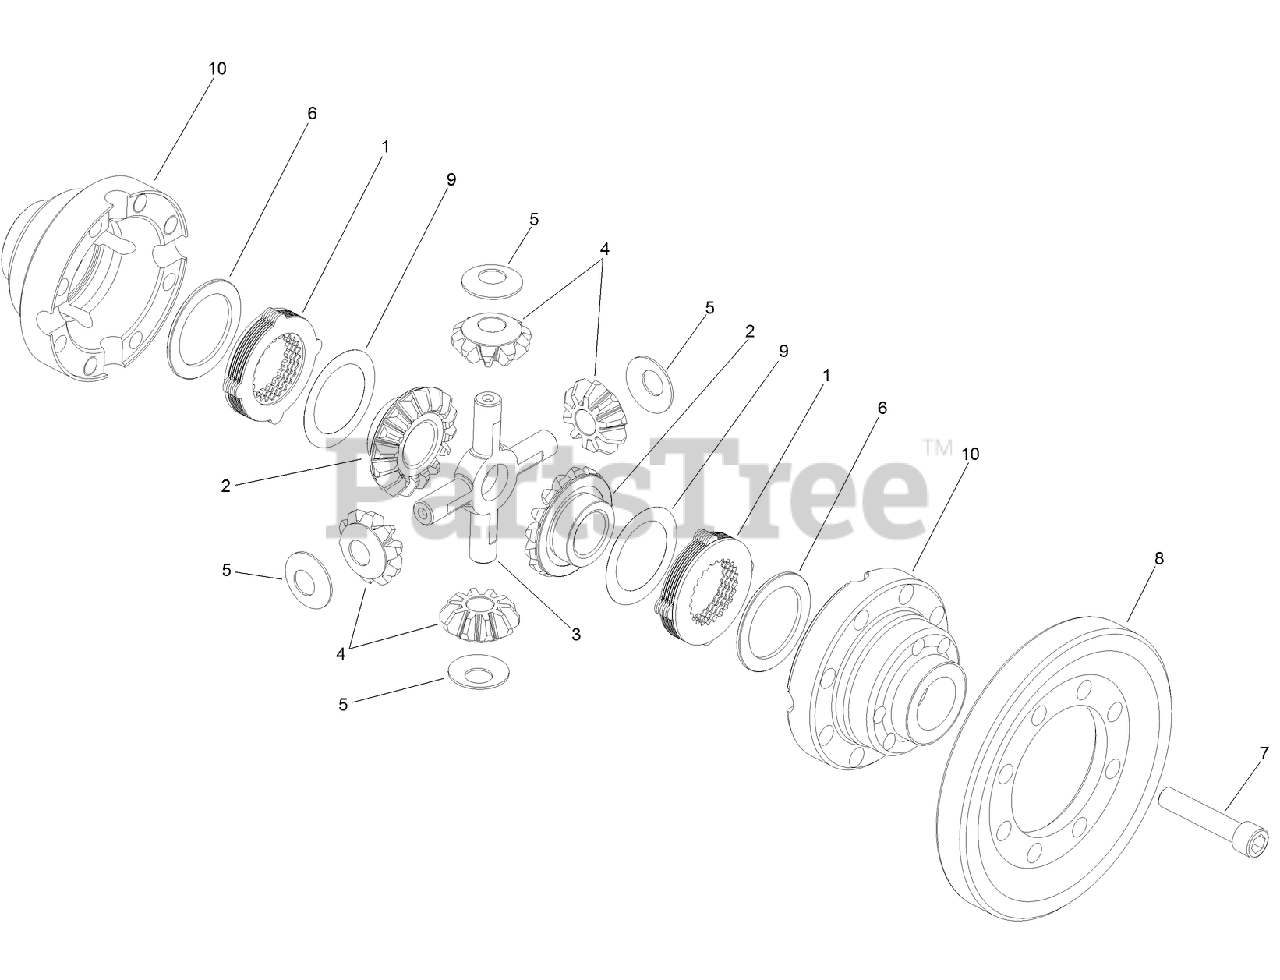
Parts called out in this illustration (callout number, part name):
1	PACKAGE-DISC
2	WHEEL-CROWN
3	GEAR-SPIDER
4	PINION-SIDE
5	SHIM-PINION, SIDE
6	WASHER-PINION
7	SCREW-SOCKET
8	CROWN-BEVEL
9	SHIM (0.2)
10	HOUSING-DIFFERENTIAL
